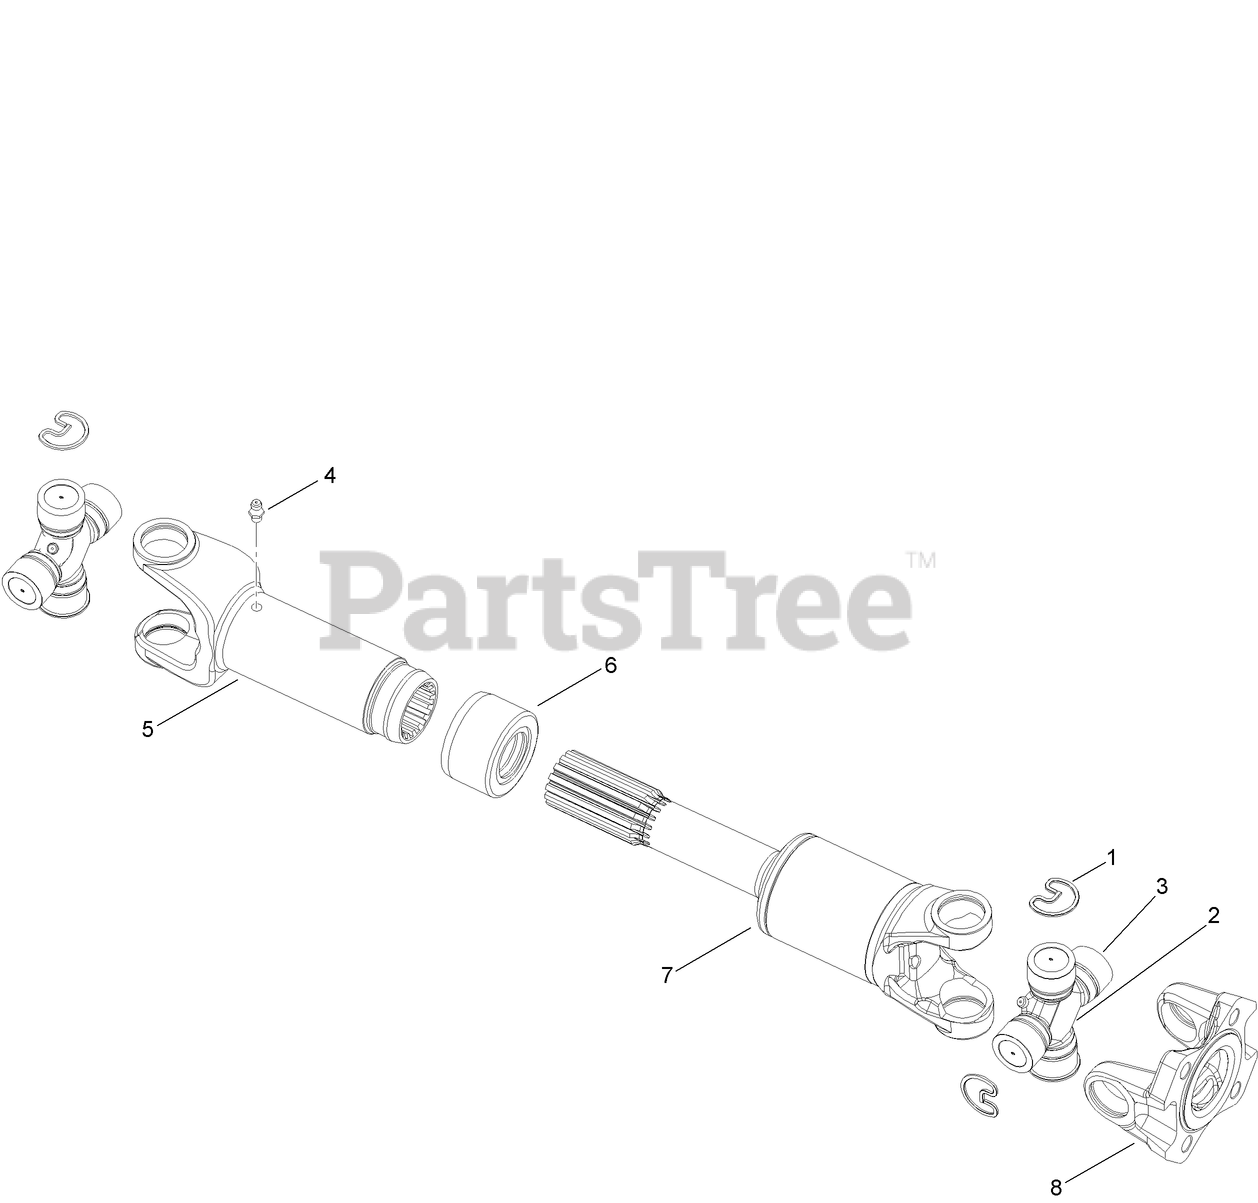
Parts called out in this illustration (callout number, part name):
1	RING-RETAINING
2	JOURNAL
3	Cup-Bearing
4	FITTING-LUBE
7	Shaft
